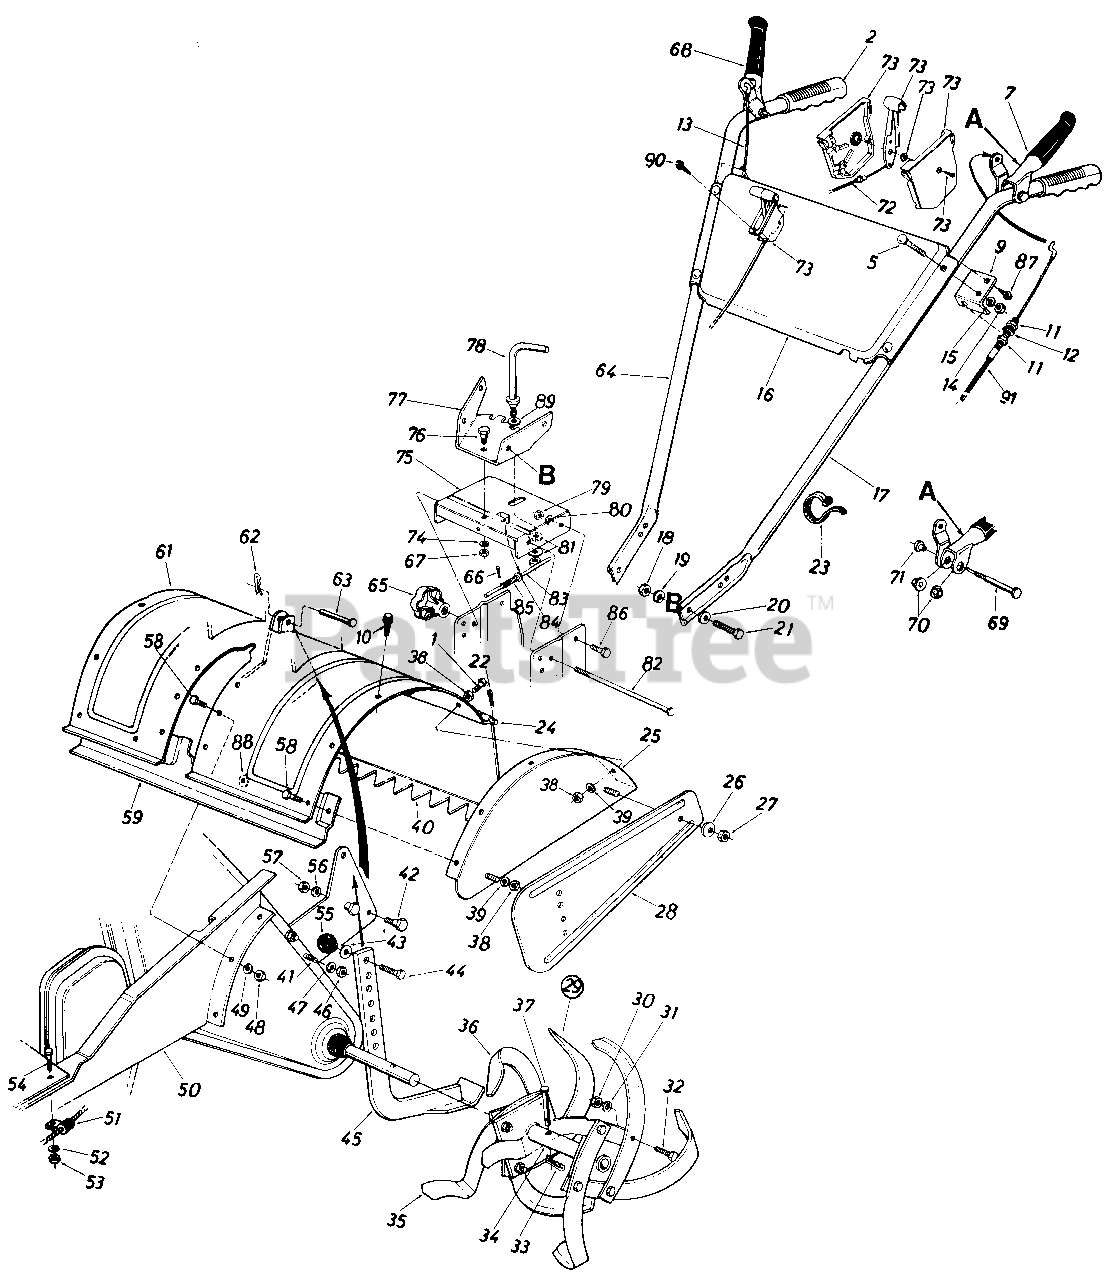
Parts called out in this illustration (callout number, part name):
1	Hex Bolt 5/16-18 x 11/4" Lg.
2	Grip
5	Carr. Bolt 5/16-18 x 1.75"
7	Clutch Grip Ass'y.-L.H.
9	Clutch Cable Bracket
10	Hex Wash. S-Tap Scr. 5/16-18 x .62" Lg.
11	Hex Nut 5/16-24 Thd.
12	L-Wash. 5/16" I.D.*
13	Wheel Drive Cable
14	Hex Nut 5/16-18 Thd.
15	L-Wash. 5/16" I.D.
16	Handle Panel
17	Handle-L. H .
18	Hex Nut 3/8-16 Thd.
19	L-Wash. 3/8" I.D.
20	Bell-Wash. 3/8" I.D.
21	Hex Bolt 3/8-16 x 1.00" Lg.
22	Cotter Pin 3/32" Dia. x 3/4"
23	Cable Tie
24	Tiller Flap Rod
27	Hex Nut 5/16-18 Thd.
31	L-Wash. 3/8" I.D.
32	Hex Bolt 3/8-24 x 1.25" Lg.
33	Hairpin Cotter
38	Hex Nut 5/16-18 Thd.
39	L-Wash. 5/16" I.D.
41	Hex Bolt 5/16-18 x 1.0" Lg.
42	Shld. Bolt 1/2" Dia. x .426"
43	Fl-Wash. 3/8" I.D. x 5/8" O.D.
44	Hex Bolt 3/8-16 x 3/4" Lg.
46	Hex Nut 5/16-18 Thd.
47	L-Wash. 5/16" I.D.
48	Hex Nut 5/16-18 Thd.
49	L-Wash. 5/16" I.D.*
52	L-Wash. 5/16" I.D.
53	Hex Nut 5/16-18 Thd.
54	Hex Bolt 5/16-18 x 3/4" Lg.
55	Ball Knob 1-1/4" Dia.
56	L-Wash. 3/8" I.D.
57	Hex Nut 3/8-16 Thd.
58	Hex Bolt 5/16-18 x .75" Lg.
63	Clevis Pin 3/8" Dia.
64	Handle-R.H.
65	Hand Knob
66	Cotter Pin 1/16" Dia. x ,75n Lg.
67	Hex Cent. L-Nut 3/8-16 Thd.
68	Clutch Grip Ass'y.-R.H.
69	Shoulder Bolt .38n Dia. x 1.53" Lg.
70	Hex Flange Plastic Bearing
71	Shoulder Nut 1/4-20 Thd.
72	Throttle Control Wire
73	Throttle Control Box Ass'y.
74	Bell-Wash. .40" I.D.
79	Hex Cent. L-Nut 3/8-16 Thd.
80	Bell-Wash. .40" I.D. x .88" O.D.
81	Bell-Wash. 1/2n I.D. x l.oOn O.D.
82	Lock Pin 5/16n Dia. x 8n
83	Lower Sliding Ass'y.
84	Fl-Wash. .291" I.D. x .62" O.D.
85	Compression Spring .86" O.D. x 1.00" Lg.
86	Shoulder Bolt 1/2" Dia. x .1 70" Lg.
87	Hex Wash. S-Tap Scr. 1/4-20 x 50n Lg
88	Bell-Wash. 5/16 I.D.
89	Fl-Wash. 5/8" I.D.
90	Self-Tap Scr. #10 x 1/2" Lg.
91	Tine Control Cable
